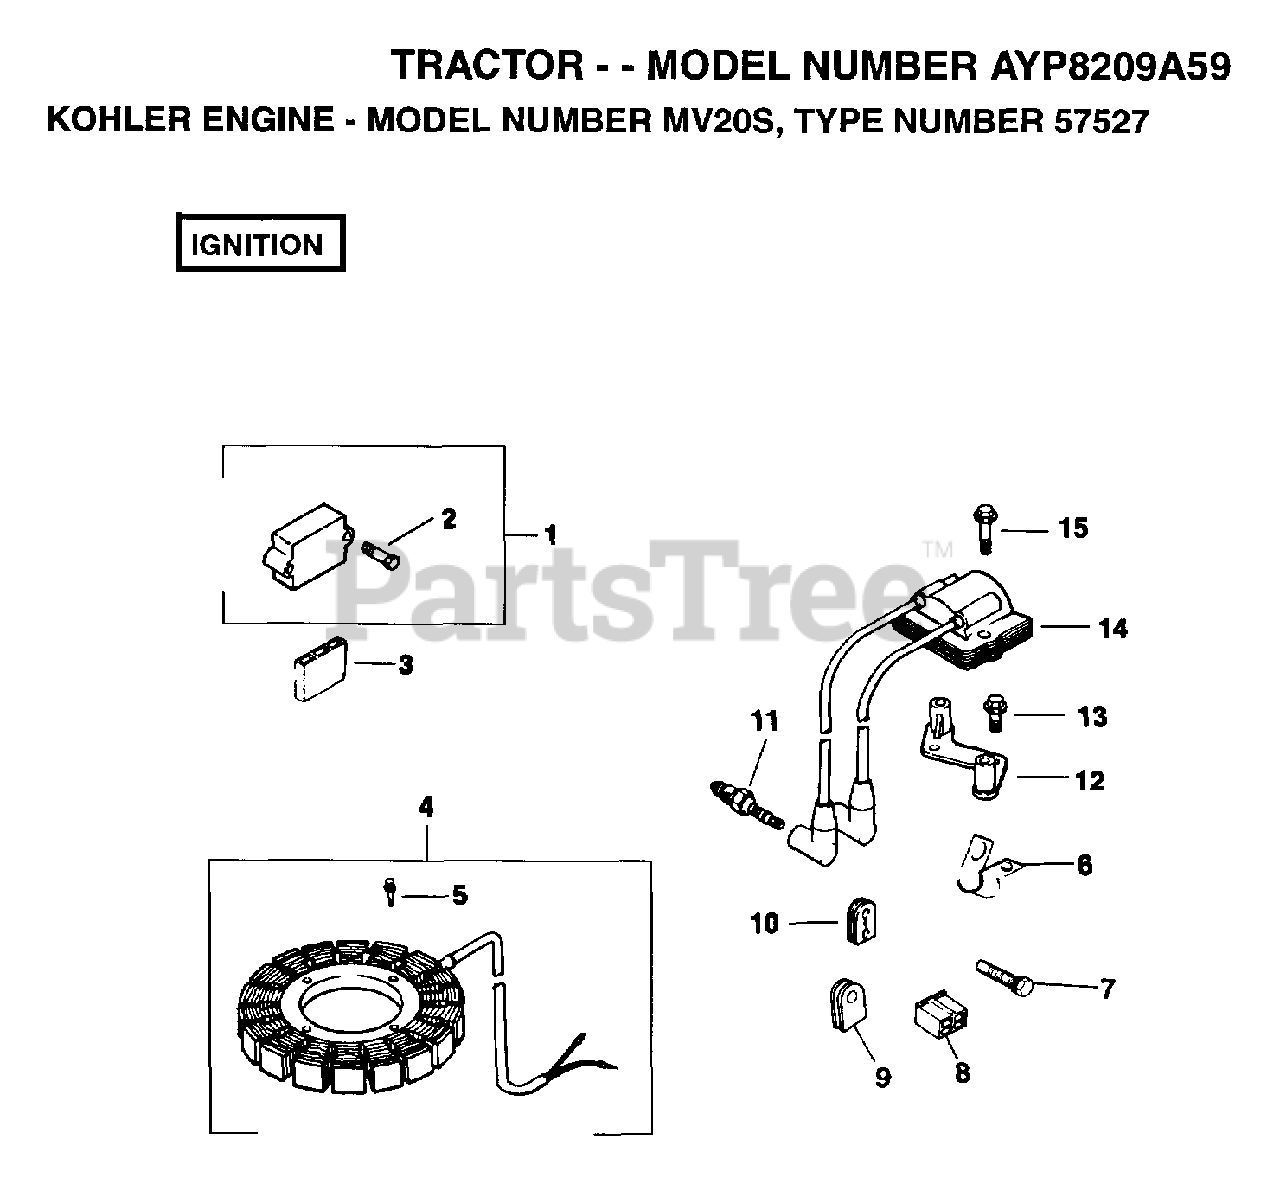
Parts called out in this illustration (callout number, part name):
2	SCREW
3	CONNECTOR
4	KIT
5	SCREW
6	CLIP
7	SCREW
8	CONNECTOR
9	GROMMET
13	SCREW, 1/4-20 X 1
